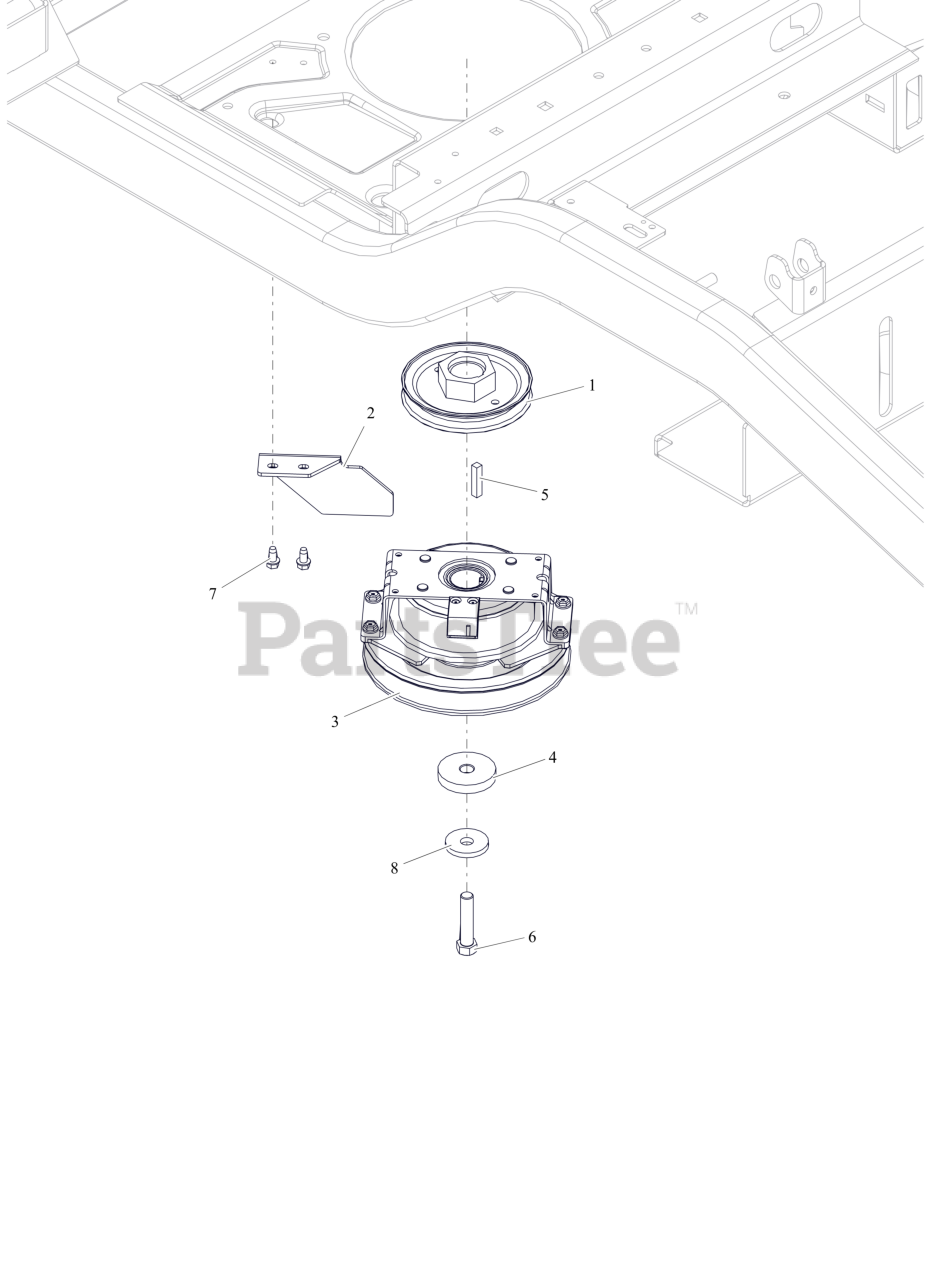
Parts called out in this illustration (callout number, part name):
1	WLDMT,PULLEY-4.50ODX1.127
2	BRKT, CLUTCH STOP HD
3	CLUTCH, OGURA DBLS SPRG 1.13"
4	SPACER, .474/.459X2.00X.350
5	KEY-SQ .25 X 1.25 X .25 SAE
6	BLT, HEX .44-20X2.00 G8 ZCC NT
7	SCR-TAP .25-20X.50 HWH ZCC
8	WASHER, 7/16" SPRING DISK
